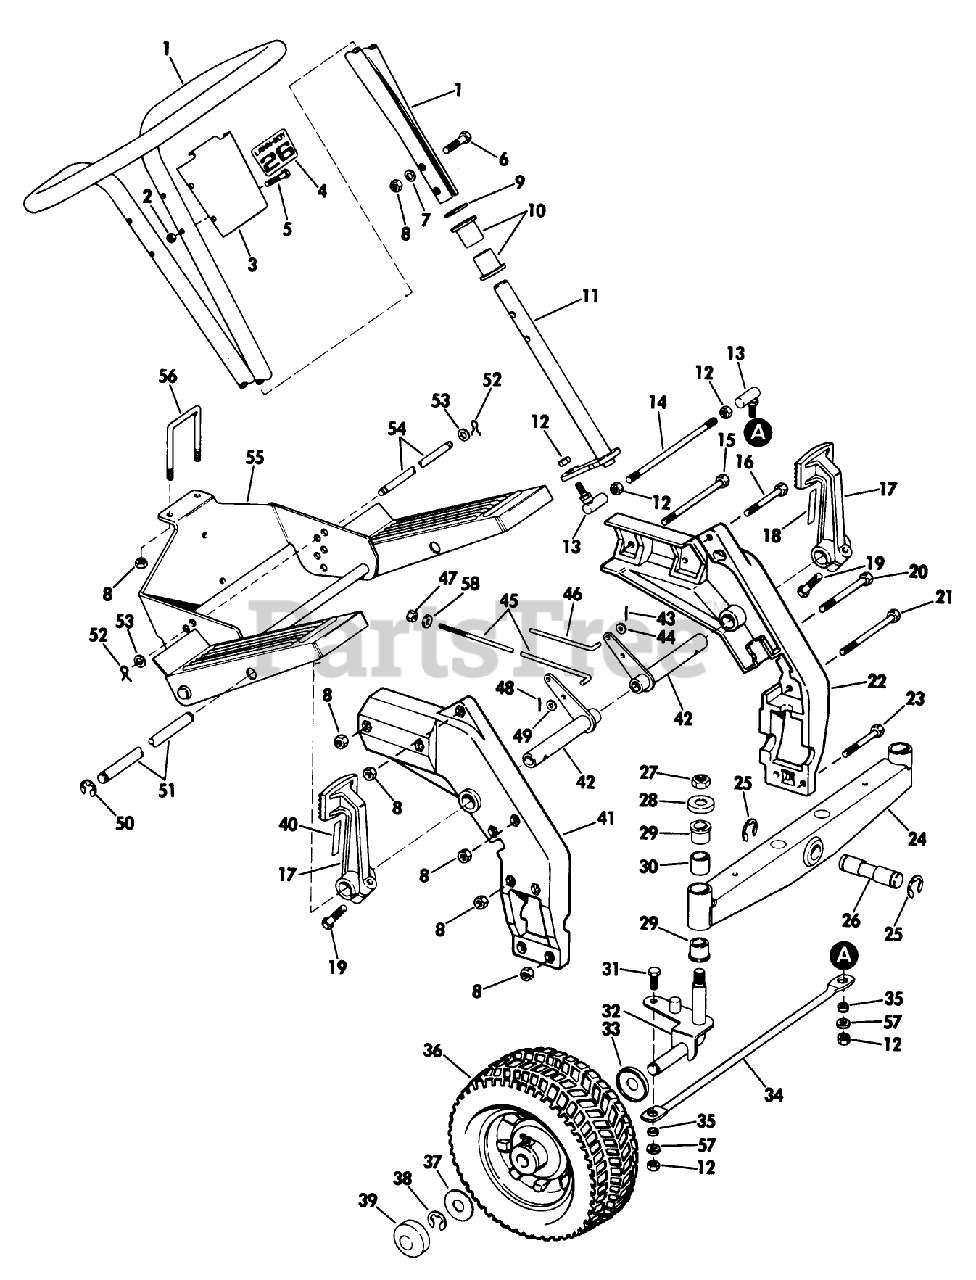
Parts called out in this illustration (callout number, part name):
2	STOP NUT
12	Jam Nut
16	Screw-Seat Support
31	Screw-King Pin
52	HAIR PIN
